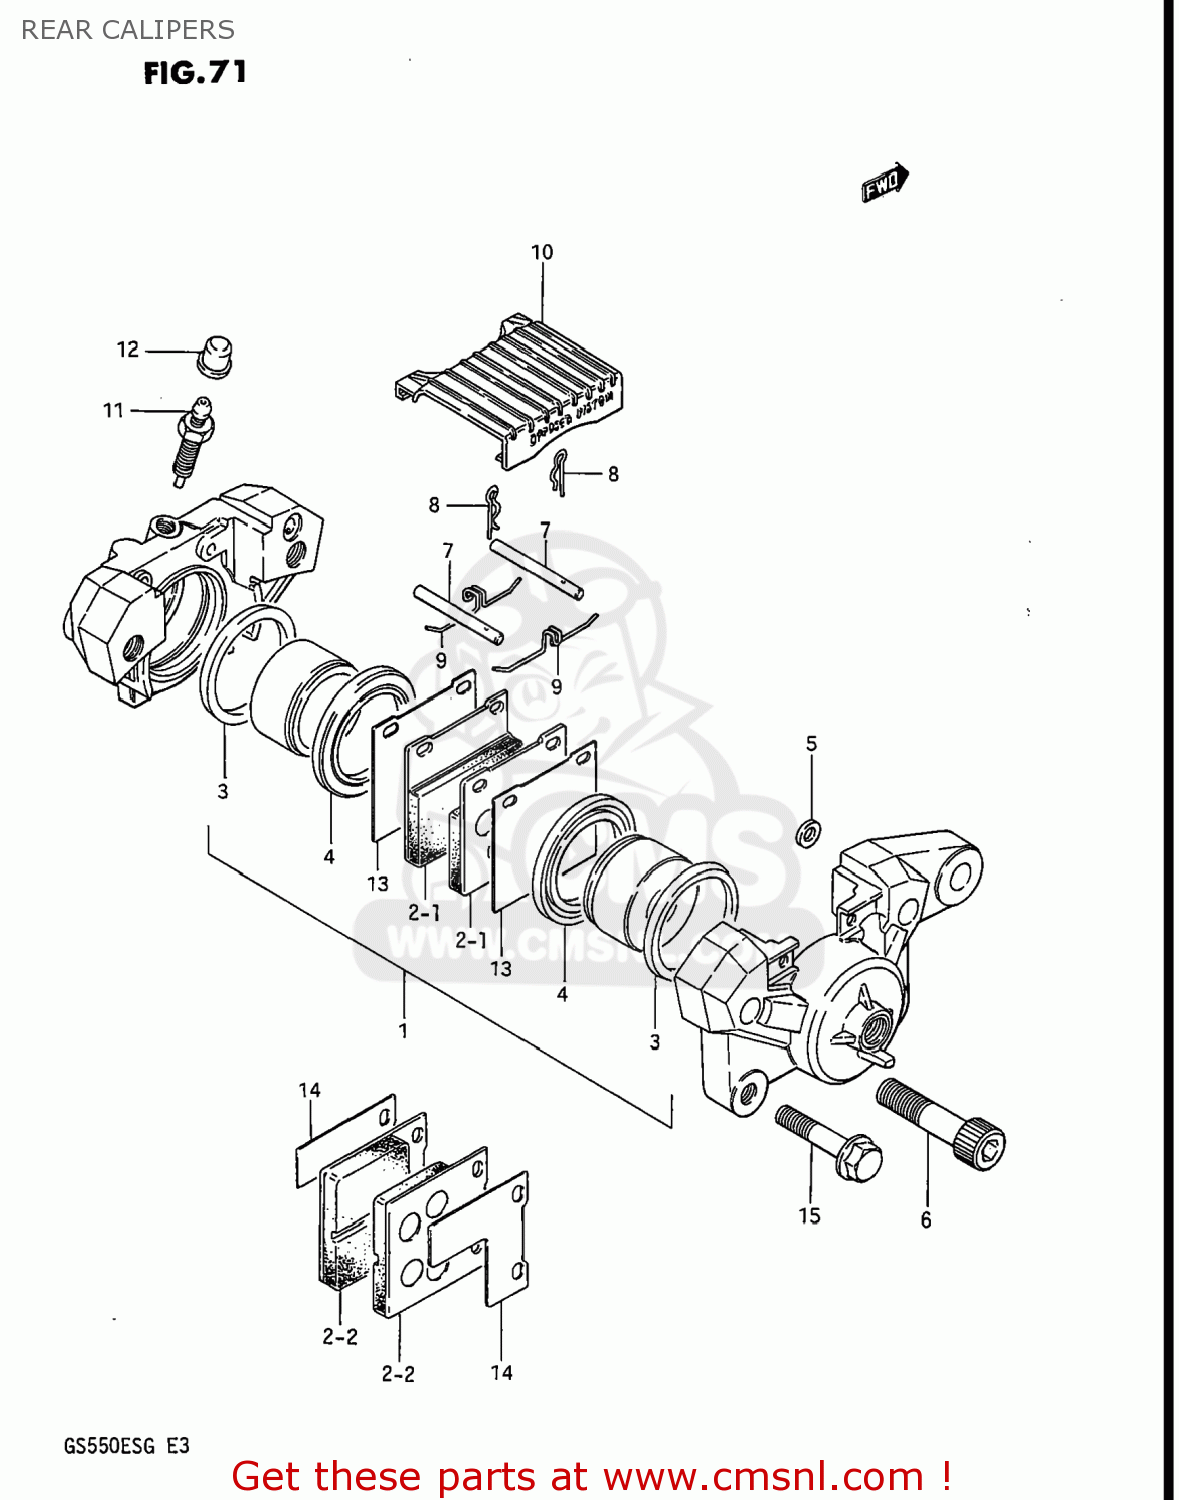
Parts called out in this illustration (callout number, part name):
1	PISTON SET
2	PAD
3	SEAL,PISTON
4	BOOT
5	SEAL,JOINT
6	BOLT,CALIPER HOUSING
7	PIN,PAD
8	CLIP,PAD PIN
9	SPRING
10	COVER,CALIPER
11	BLEEDER
12	CAP,BREATHER
13	SHIM,PAD
14	SHIM
15	BOLT
